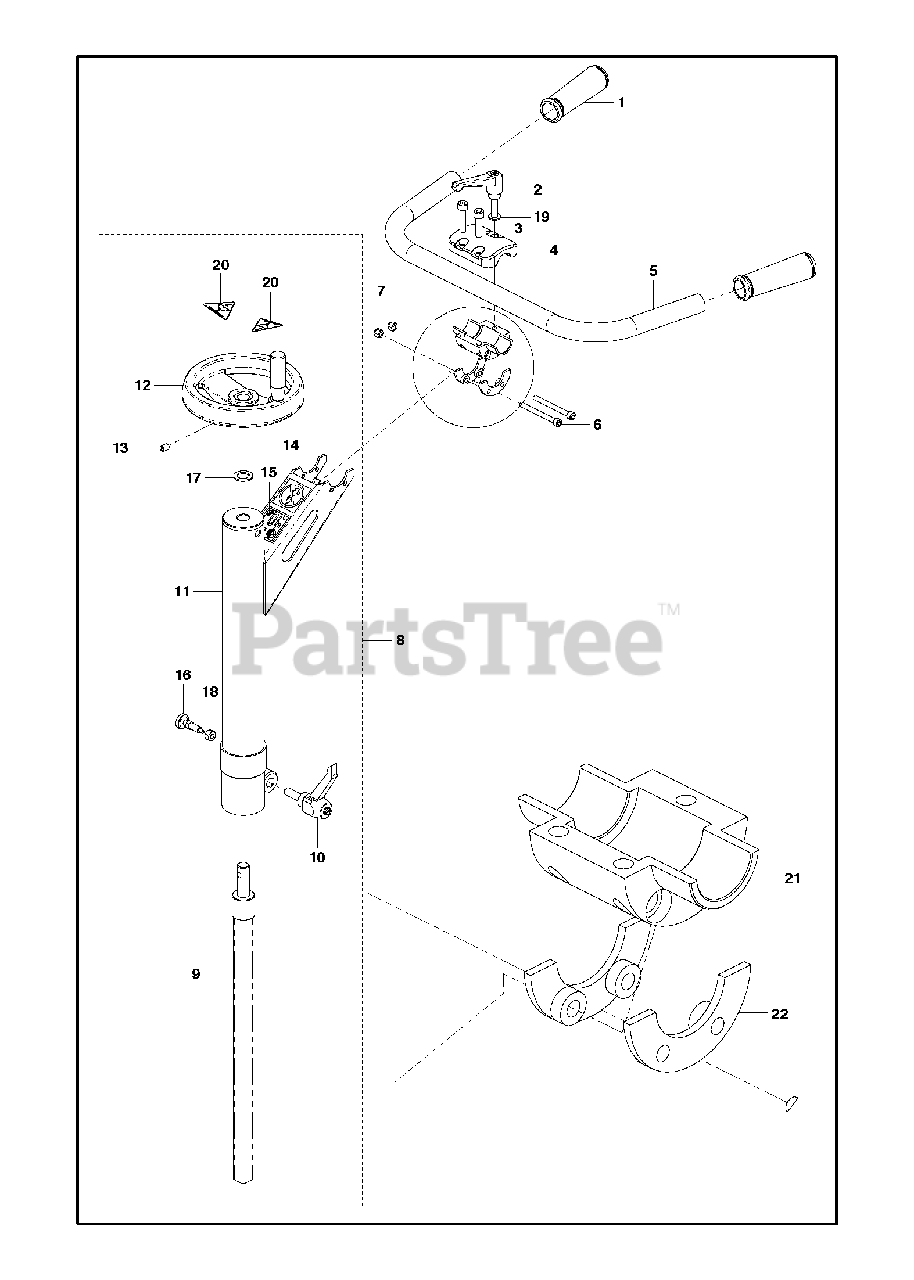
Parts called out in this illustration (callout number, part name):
7	HEXAGON LOCKING NUT
16	POSITION SPRING
19	WASHER
